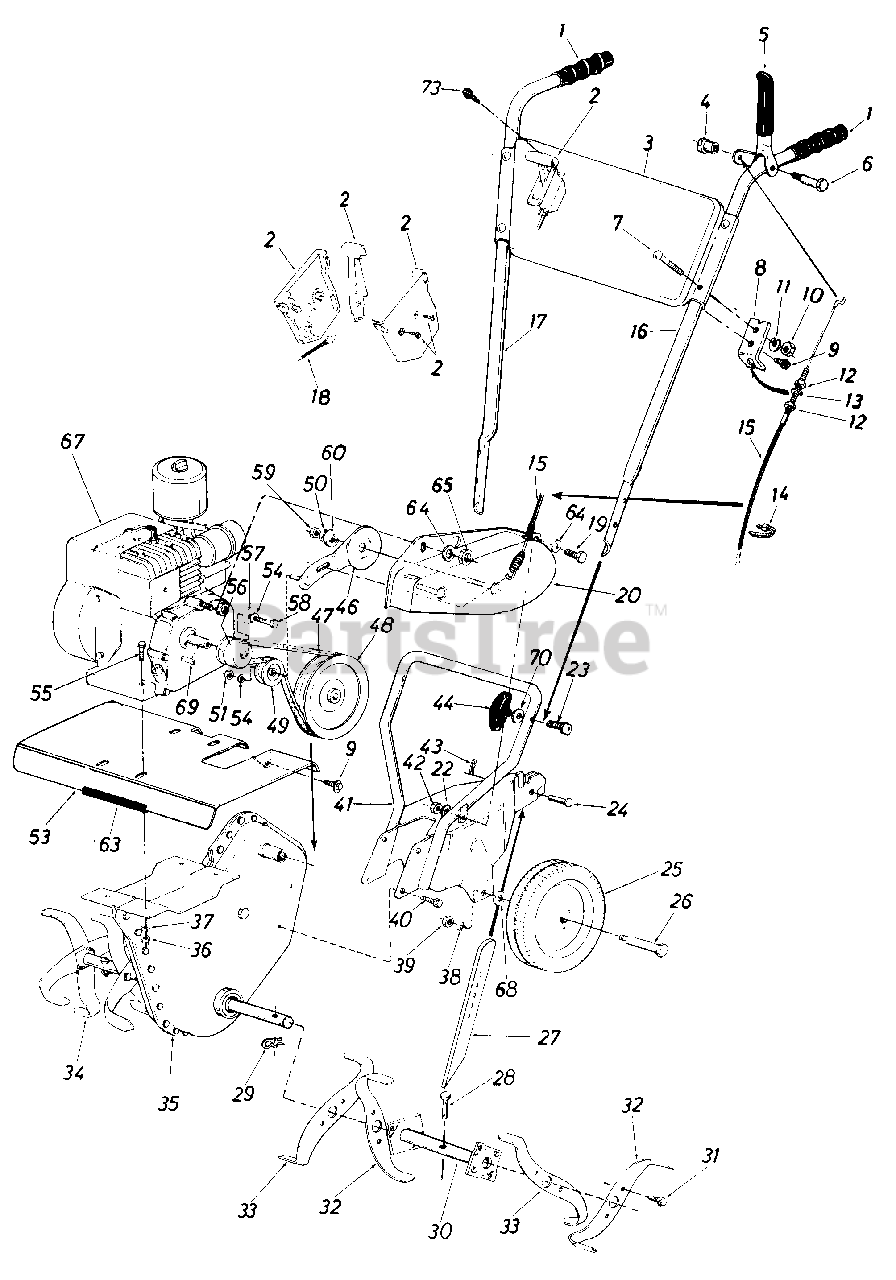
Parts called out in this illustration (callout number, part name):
2	Throttle Control Box Ass'y.
3	Handle Panel
4	Shoulder Nut
5	Clutch Grip Ass'y.
6	Shoulder Bolt 3/8 x 1.160" Lg.
7	Carriage Bolt 5/16-18 x 1.5" Lg. *
8	Cable Support Bracket
9	Hex Wash. Hd. Self-Tap Scr. 1/4-20 x .50" Lg.
10	Hex Nut 5/16-18 Thd.*
11	L-Wash. 5/16" I.D.*
12	Hex Jam Nut 5/16-24 Thd.
13	L-Wash. 5/16" I.D.*
14	Cable Tie
15	Clutch Control Cable
19	Hex Bolt 1/4-20 x .75" Lg.*
20	Belt Cover Ass'y.
22	L-Wash. 1/4" I.D.*
23	Curved Hd. Bolt 5/16-18 x 1.75" Lg.
24	Clevis Pin
25	Wheel Ass'y. Comp.Plastic
26	Shoulder Bolt
29	Hairpin Coter
36	Hex Nut 5/16-18 Thd.
37	L-Wash. 5/16" I.D.
38	L-Wash. 3/8" I.D.
39	Hex Cent. L-Nut 3/8-16 Thd.
40	Hex Wash. Hd. Self-Tap Scr. 5/16-18 x .50" Lg.
43	Internal Coter Pin
44	Hand Knob
46	Idler Arm Ass'y.
47	Belt 3/8" x 29" Lg.
48	Chain Case Pulley 5-1/2 x 1/2"
49	Fl-ldler 2"
50	L-Wash. 5/16" I.D.
51	Hex Nut 3/8-24 Thd.*
55	Hex Bolt 5/16-18 x 1.50" Lg.
56	Engine Pulley 3/8 V x .75 I.D. x 2" O.D.
57	Fl-Wash. .385" I.D. x 1.00" O.D.
58	Hex Bolt 3/8-24 x 1.00" Lg.
59	Hex Nut 5/16-18 Thd.
60	Shld. Spacer .50" Dia. x .133
63	Trim Strip-4"
64	Fl-Wash. .281" I.D. x .500" O.D.
65	Hex Cent. L-Nut 1/4-20 Thd.
67	Engine
68	Bell-Wash.
69	Square Key 3/16 x 3/4" Lg.
70	Bell-Wash.
73	Self-Tap Screw #10 x .5" Lg.
